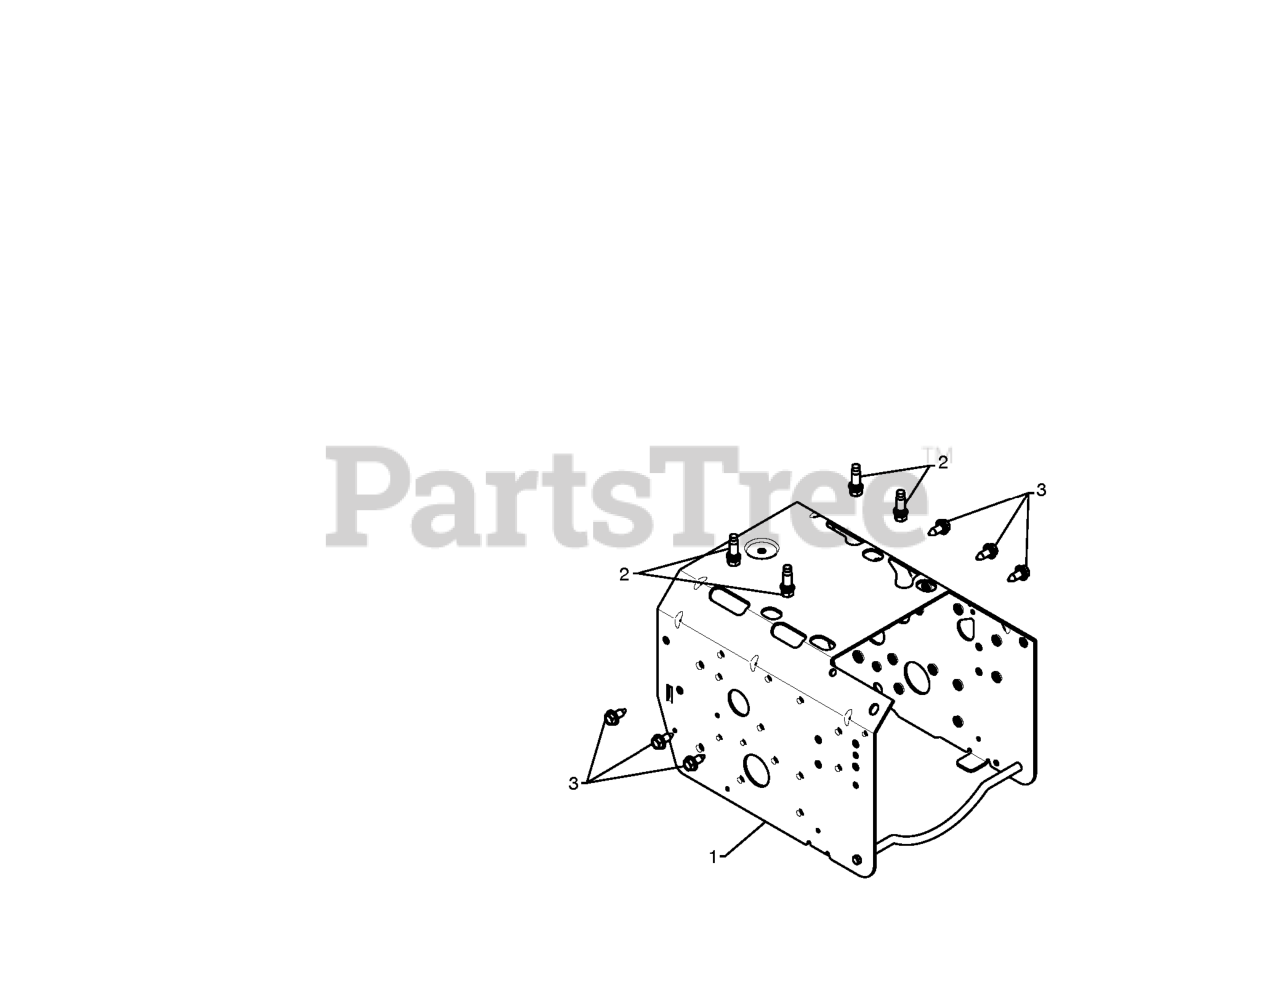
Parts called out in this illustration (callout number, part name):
1	FRAME.WELD.PNT.GEAR.ORANGE
2	BOLT 3/8-16X1-1/8
3	BOLT.HEX.HD.WASHER.5/16-18X.75
